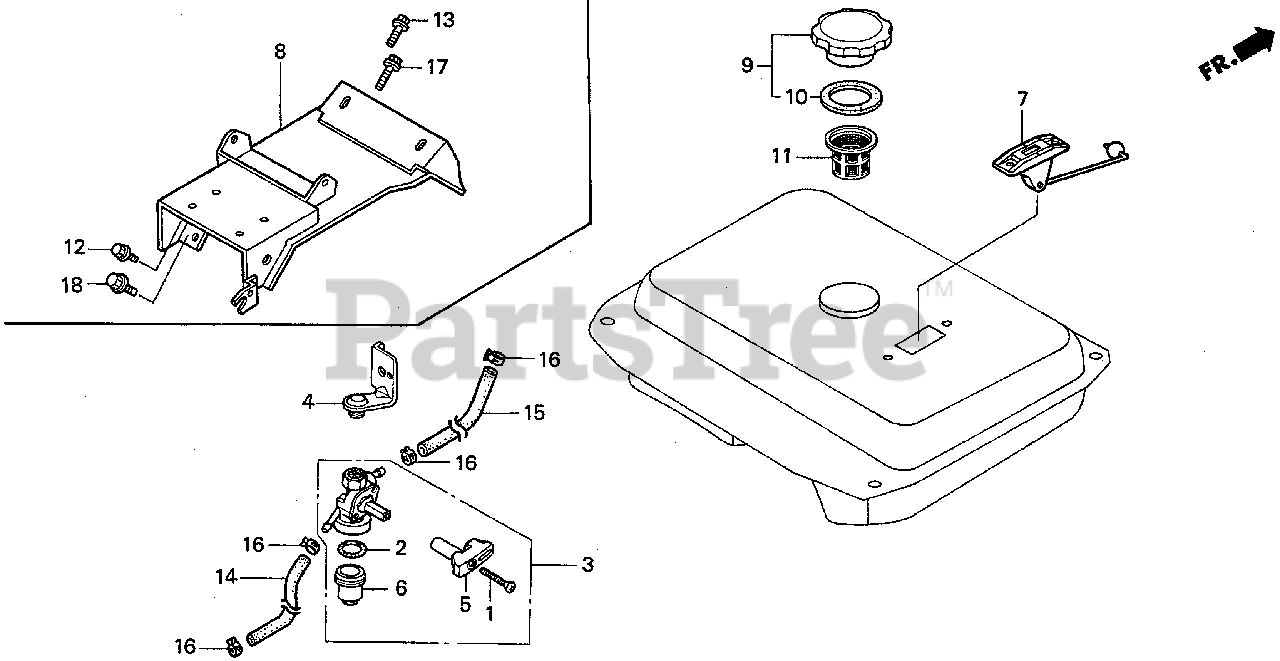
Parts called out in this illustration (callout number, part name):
8	STAY, FUEL TANK
12	BOLT, FLANGE (6X23)
13	BOLT, FLANGE (6X20) (CT200)
17	BOLT, FLANGE (8X25)
18	BOLT, FLANGE (8X30)
